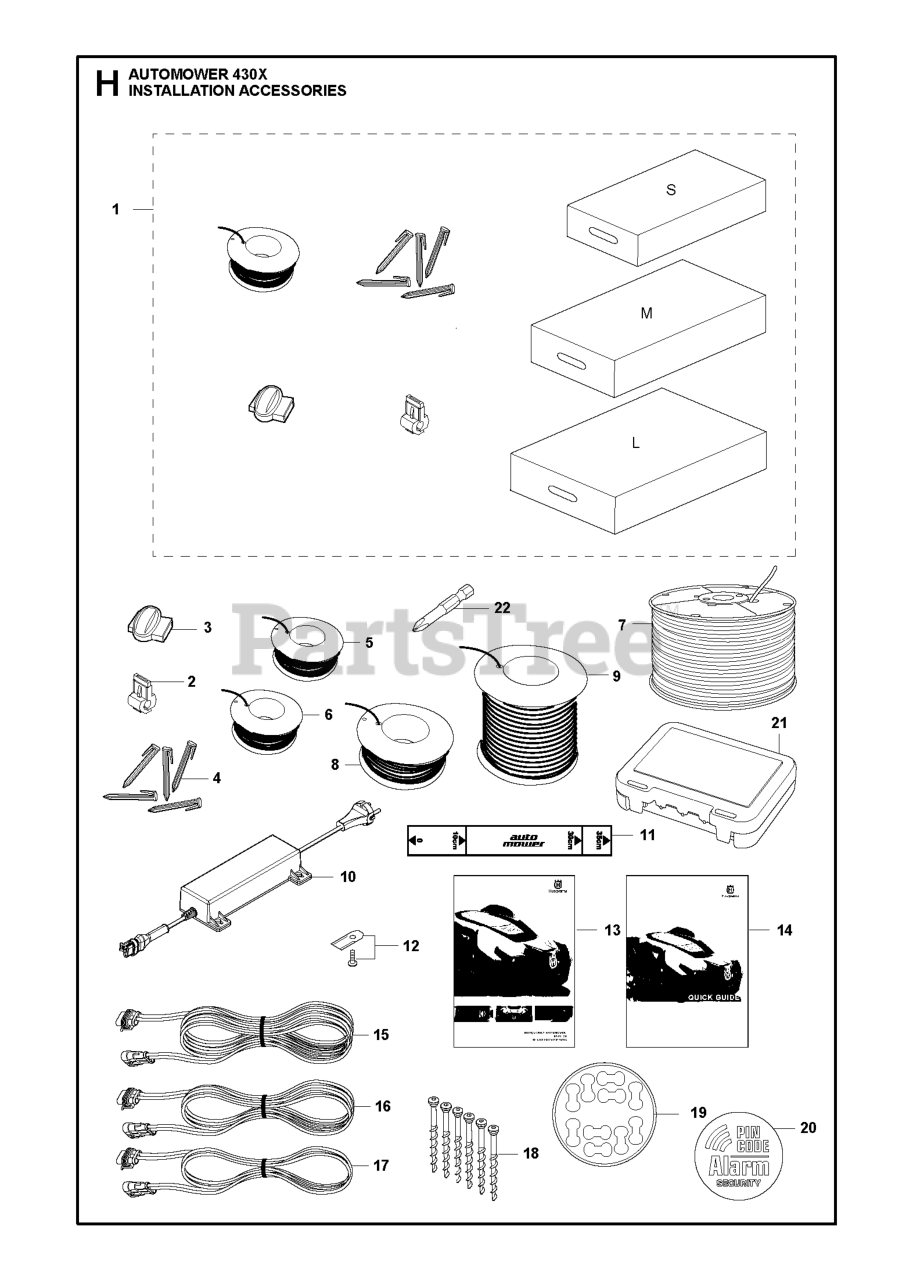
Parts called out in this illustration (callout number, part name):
1	SMALL AUTOMOWER INSTALL KIT
1	LARGE AUTOMOWER INSTALL KIT
1	MED AUTOMOWER INSTALL KIT
2	CONNECTOR 5 PCS, BLISTER
2	BRAKER
2	CONNECTOR 100 PCS
3	COUPLER SPLICER, 100 PCS
3	COUPLER SPLICER, 5 PCS,
3	SPLICE KIT
4	STAPLE 100 PCS, BLISTER
5	WIRE 150M, BLISTER
5	WIRE 50M STANDARD Ø2.7MM,BLIST
5	WIRE BOUNDARY 150M
6	WIRE 250M
8	WIRE 500M
9	WIRE (800M)
10	Power Unit
11	RULER / CENTIMETERS
12	HUS BLADE SET 9 PCS
12	HUS BLADE SET 45 PCS
12	HUS BLADE SET 300 PCS
15	CABLE ASSY LOW VOLTAGE CABLE
16	CABLE ASSY LOW VOLTAGE CABLE
17	CABLE ASSY LOW VOLTAGE CABLE
18	Screws
19	STICKER CABLE MARKERS KIT 10PC
20	LABEL SECURITY
21	CONNECTOR PROTECTION BOX
22	WRENCH BITS CHANGING ROBOTIC B
